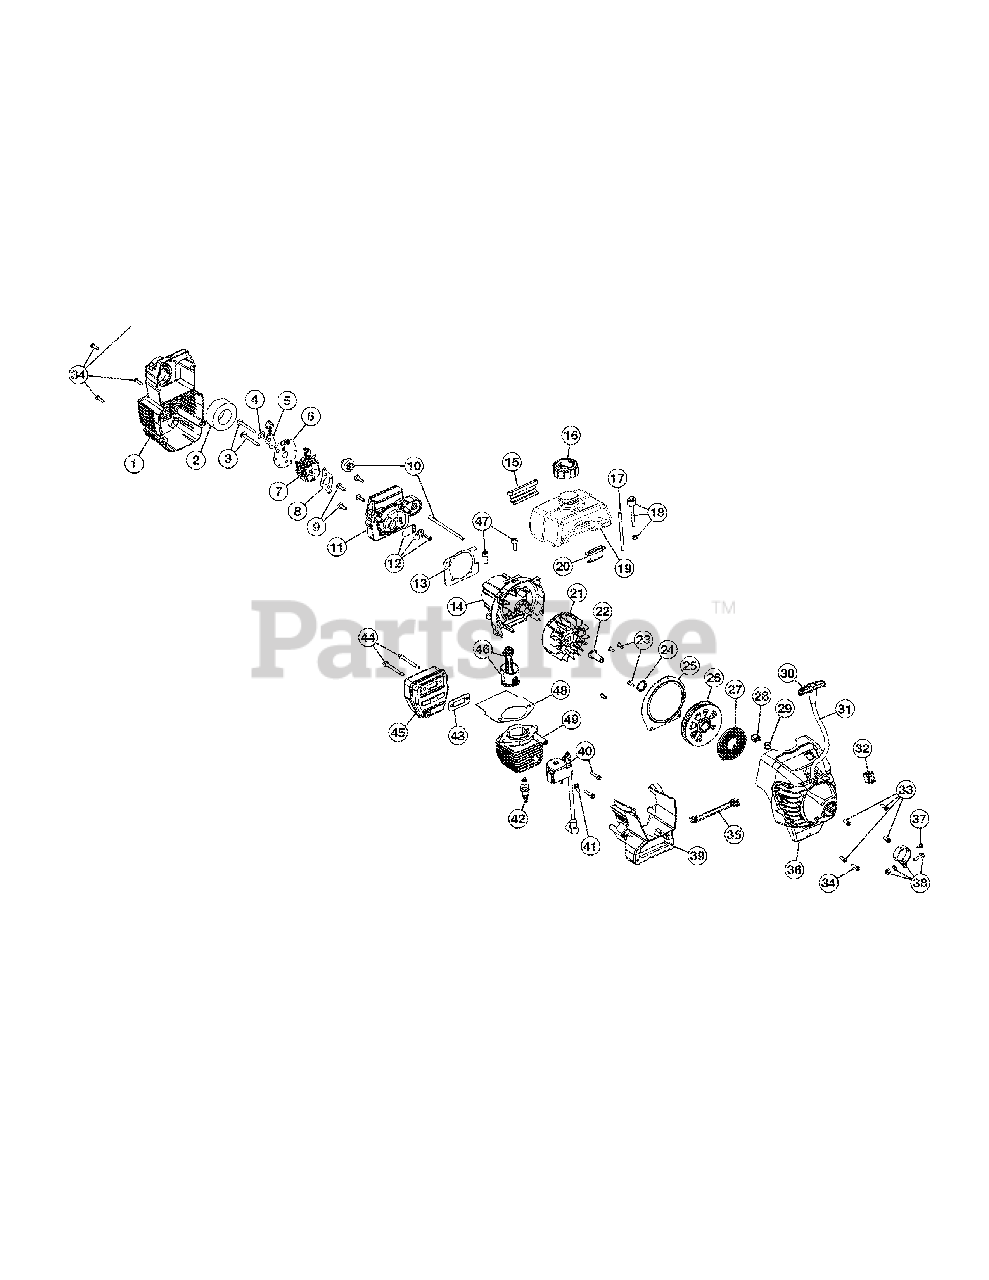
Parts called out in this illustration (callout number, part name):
1	Air Cleaner Cover Assembly (includes 2 & 34)
2	Air Cleaner Filter
3	Carburetor Mounting Screws
4	Wavey Washer
5	Choke Lever Assembly
6	Choke Lever & Plate (includes 5)
7	Carburetor Assembly (includes 8 & 19)
8	Carburetor Gasket
9	Carb Mount Screw
10	Primer and Hose Assembly
11	Carburetor Mount Assembly (includes 9, 12 & 13)
12	Reed Assembly
13	Carburetor Mount Gasket
14	Crankcase Service Assembly (includes 9)
15	Rear Mounting Pad
16	Fuel Cap Assembly
17	Fuel Return Line
18	Fuel Line Assembly
19	Fuel Tank Assembly (includes 16-18)
20	Front Mounting Pad
21	Flywheel Assembly
22	Square Nut Drive
23	Plate Screw
24	Palnut
25	Pressure Plate (includes 23 & 28)
26	Recoil Pulley Assembly (includes 24)
27	Recoil Spring
28	Eyelet Retainer
29	Rope Guide
30	Pull Handle
32	Switch Assembly
33	Housing Screw
34	Cover Screw
35	Wire Lead
36	Starter Housing Assembly (includes 23-35)
37	Anti-Rotation Screw
38	Clamp Assembly (includes 37)
39	Shroud Extension and Stand (includes 34)
40	Module Assembly
41	Ground Tab
42	Spark Plug
43	Exhaust Gasket
44	Muffler Mounting Bolt Assembly
45	Muffler Assembly (includes 43 & 44)
46	Piston & Rod Assembly
47	Cylinder Bolt
48	Cylinder Gasket
49	Cylinder Assembly (includes 47 & 48)
